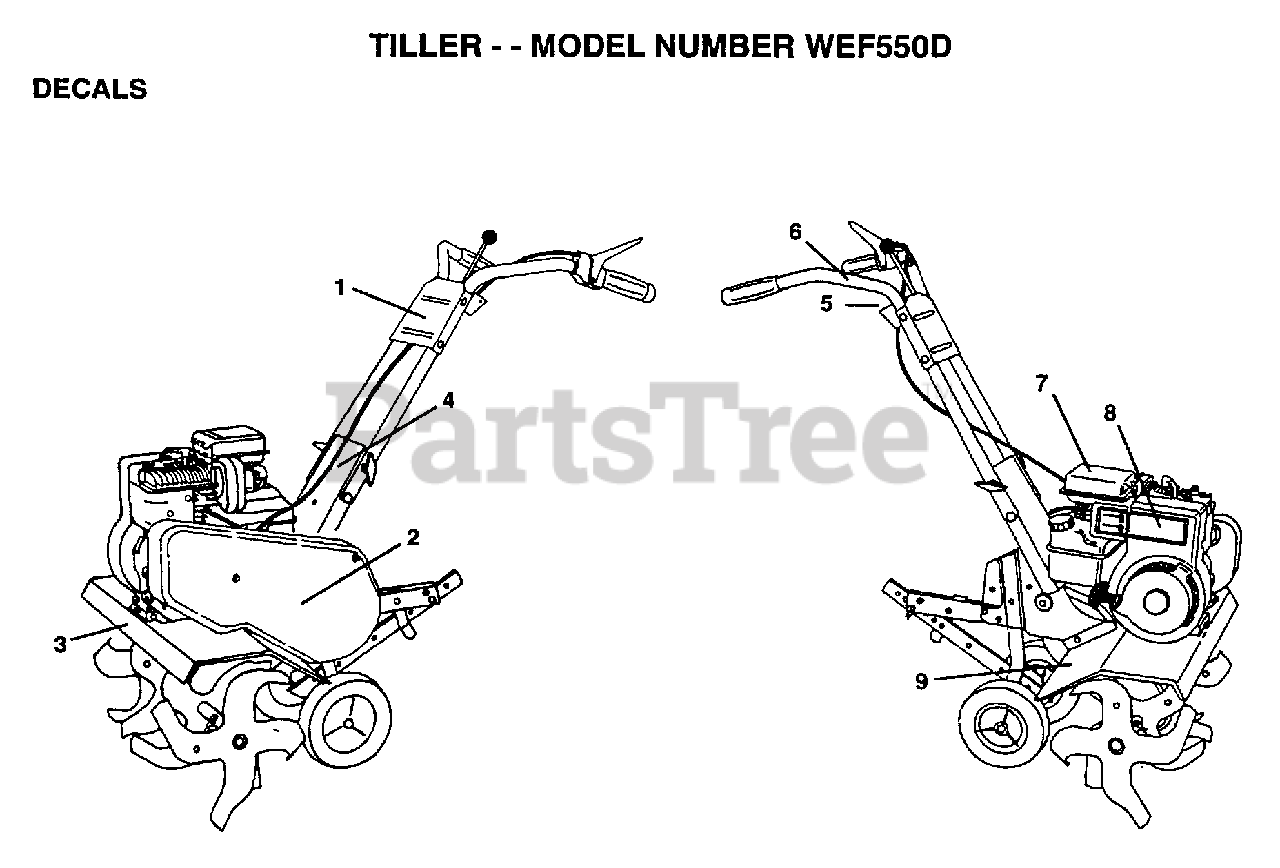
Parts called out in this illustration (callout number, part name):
2	DECAL BELTGUARD
3	DECAL.SHIELD.TINE
4	DECAL.PNL.HANDLE
5	DECAL REVERSE
6	DECAL TI
7	DECAL TI
8	DECAL, BRIGGS & STRATTON
